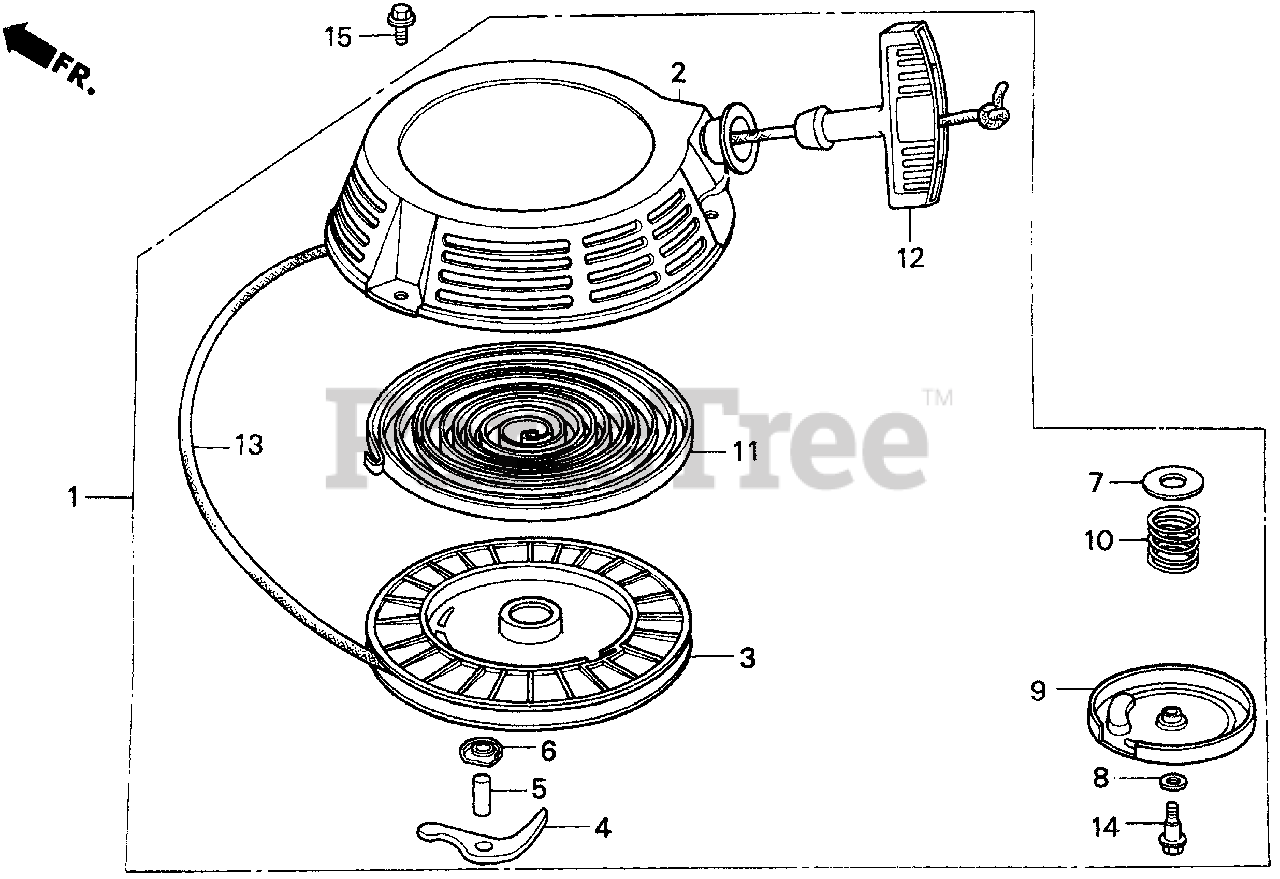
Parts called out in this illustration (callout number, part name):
1	STARTER ASSY., RECOIL *R8* (Honda Code 3415049). (BRIGHT RED)
2	CASE, RECOIL STARTER *R8* (Honda Code 3625571). (BRIGHT RED)
3	REEL, STARTER
4	RATCHET, STARTER
5	SHAFT, RATCHET
6	PLATE, GUIDE
7	PLATE A, FRICTION
8	PLATE B, FRICTION
9	COVER, REEL STARTER
10	SPRING, FRICTION
11	SPRING, RETURN
12	GRIP, STARTER
13	ROPE, STARTER (#6X64") (Honda Code 2106433). (N/A: USE ALT P/N 08560-ZG921-11)
14	BOLT, REEL COVER
15	BOLT, FLANGE (6X10)
